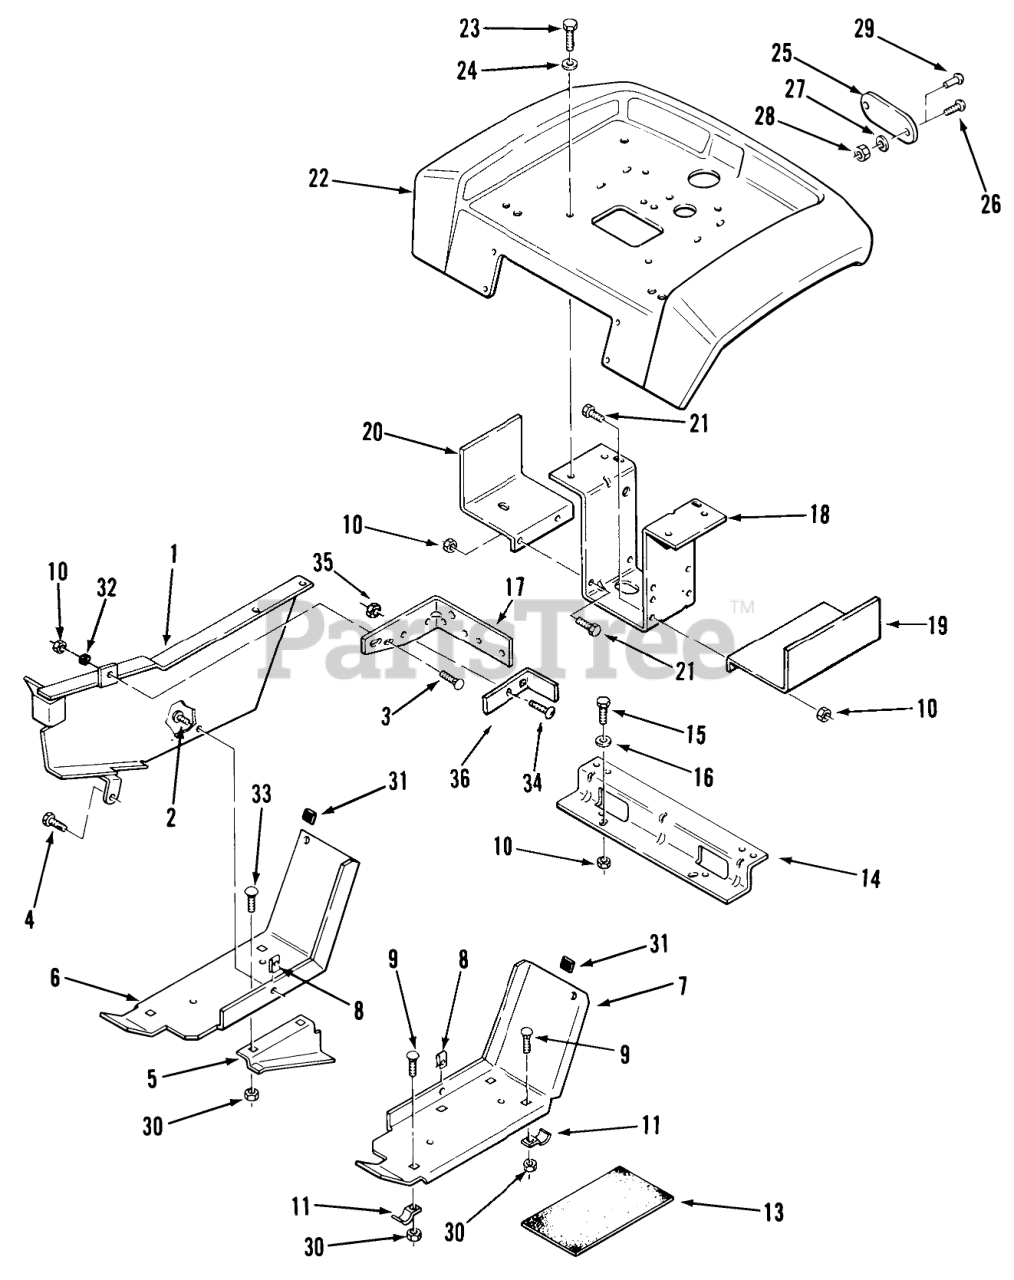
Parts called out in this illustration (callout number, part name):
1	Belt Guard
2	Screw
3	Bolt
4	SCREW
5	GUID-LOWER BLTR
6	Footrest-RH
7	FOOTREST LH R
9	Bolt
10	Nut
11	BRACKET
13	PAD FOOTREST
13	LH FOOTREST MAT
13	RH FOOTREST MAT
13	PAD-FOOTREST
14	BRACKET-FENDER B
15	Bolt
16	WASHER 5/16 SAE
17	SUPPORT-BELT GUAR B
18	Bracket-Fender Support
19	Fuel Tank Support LH
20	Support-FueITank RH
21	Bolt
22	Fender
23	SCREW
24	WASHER 5/16 SAE
25	Reflector
26	Screw
27	Lockwasher
28	Nut
29	Poprivet
30	Nut
31	BUMPER
32	NUT-PUSH
33	Bolt-Carriage
34	HWHMS 10-24 X 5/8
35	Nut
36	BRACKET FUSE
